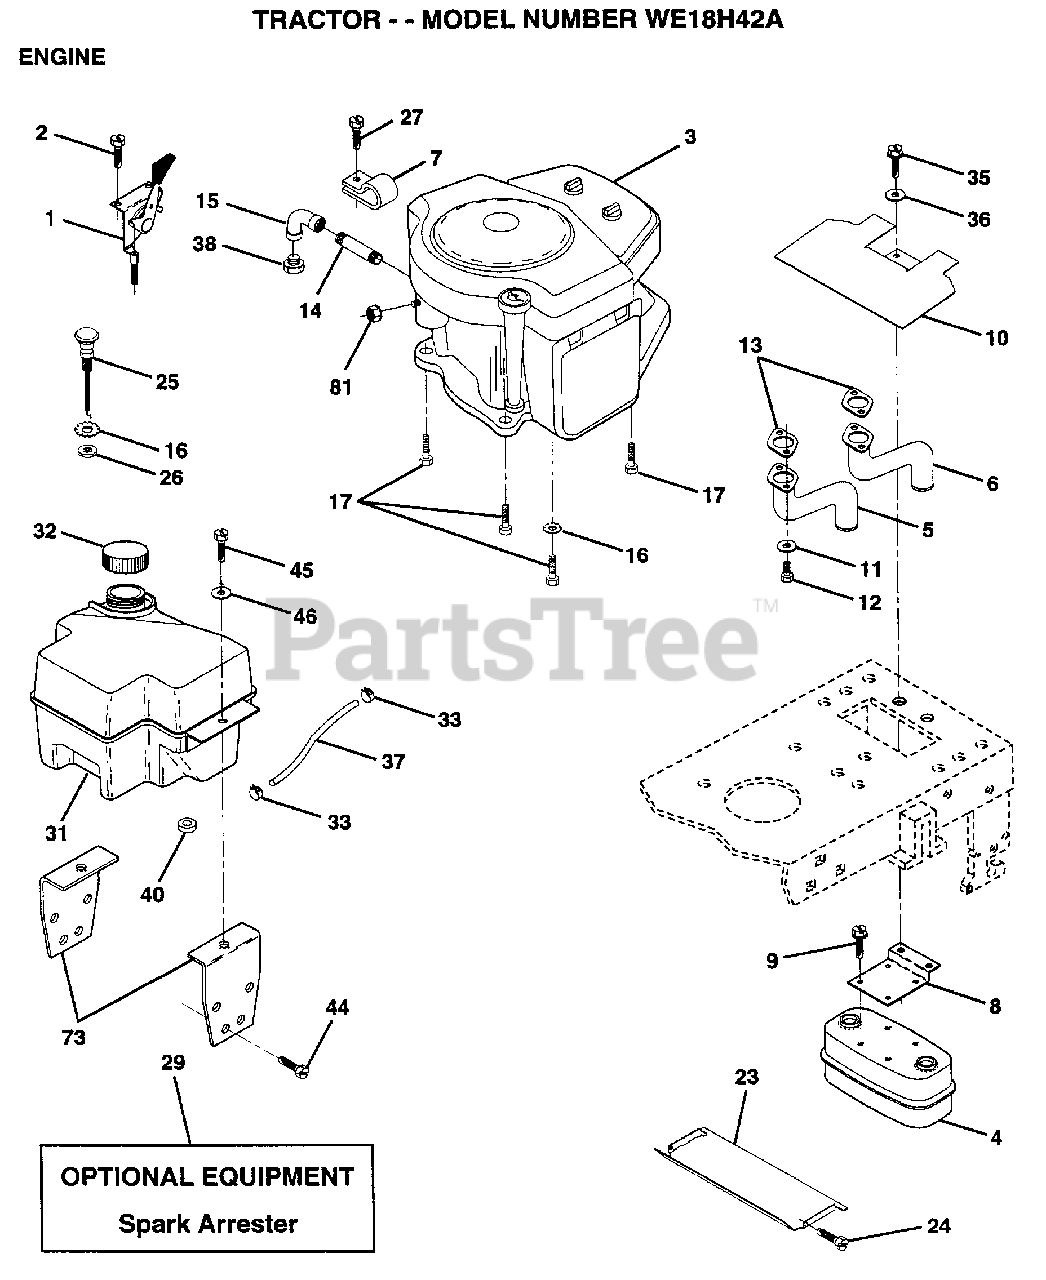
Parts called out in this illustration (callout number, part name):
2	SCREW LT
3	ENGINE B&S 18HP
5	EXHAUST.B&S.18.LH
6	EXHAUST.B&S.18.RH
7	CLAMP.TUBE.DBL.EN
8	BRACKET MUFFLER
9	SCREW ST
10	SHIELD.HEAT.
11	LOCKWASHER
13	GASKET MUFFLER
14	PIPE NIPPLE LT
15	ELBOW
16	LOCKWASHER
17	SCREW LT
23	HEAT SHIELD
24	SCREW
25	"CONTROL.CHOKE.51"""
27	SCREW.10-24X1/2
32	CAP ASM FUEL
33	HOSE CLAMP
35	SCREW
36	WASHER
37	LINE FUEL
44	SCREW
45	SCREW HEX CRT
46	WASHER
73	BRACKET.SUPT.TANK
81	NUT
